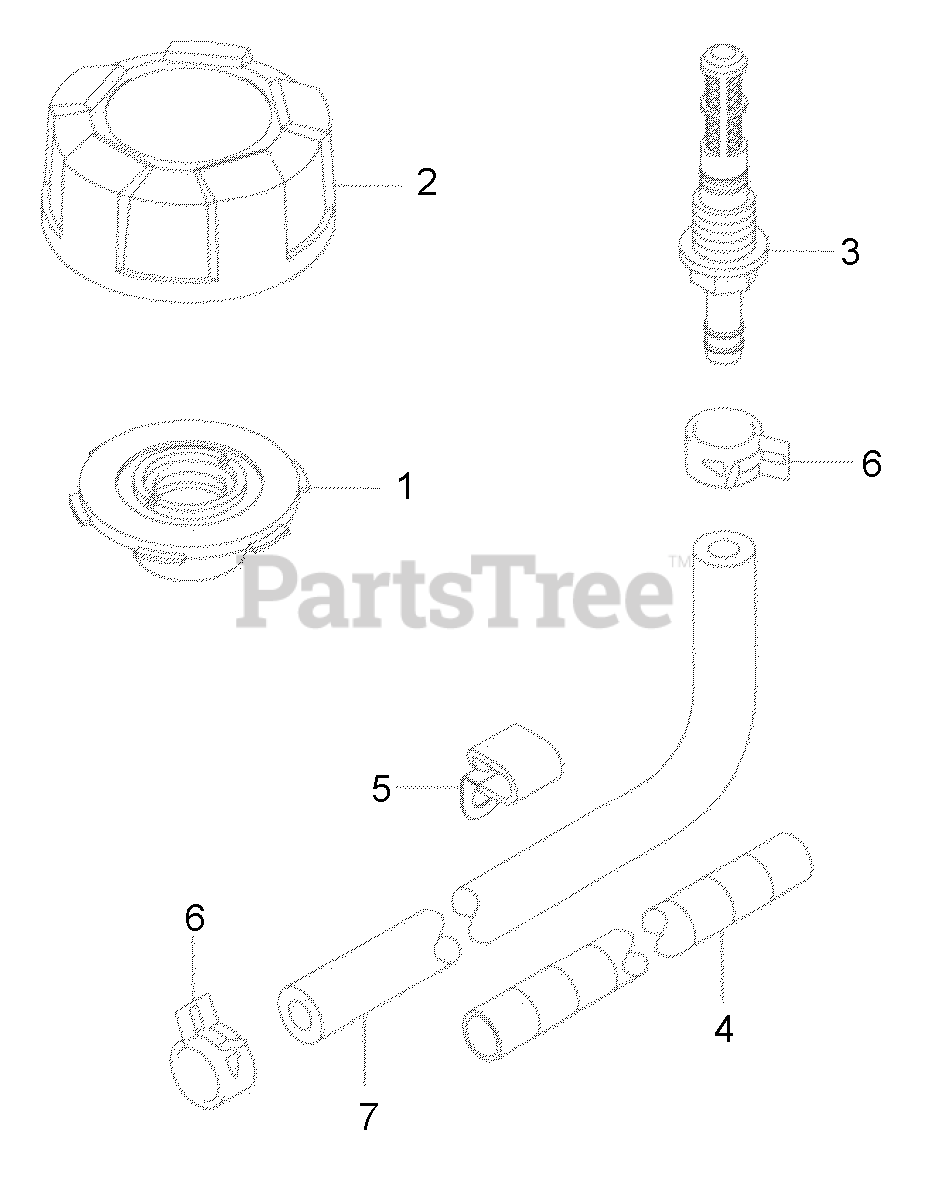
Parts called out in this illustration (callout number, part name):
3	Joint, In Tank Filter
6	Clamp
7	Tube, 6.35x12.7x285
